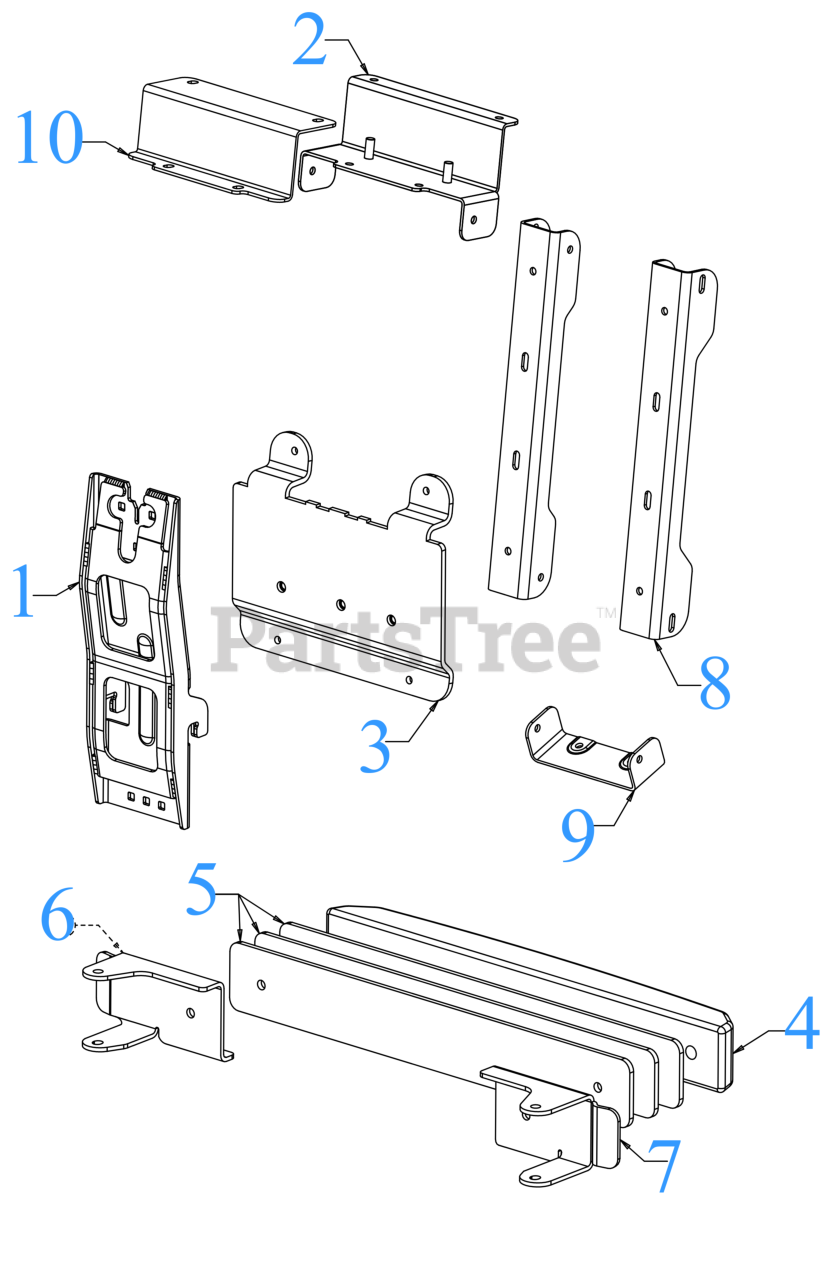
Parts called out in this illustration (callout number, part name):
1	VERTICAL SUPPORT BRACKET
2	KEEPER BRACKET
3	MOUNT PLATE
4	BAGGER WEIGHT
5	WEIGHT PLATE
6	WEIGHT BRACKET (LH)
7	WEIGHT BRACKET (RH)
8	STRUT MOUNT BRACKET
9	MOUNT BRACKET (LOWER)
10	MOUNT BRACKET (UPPER)
